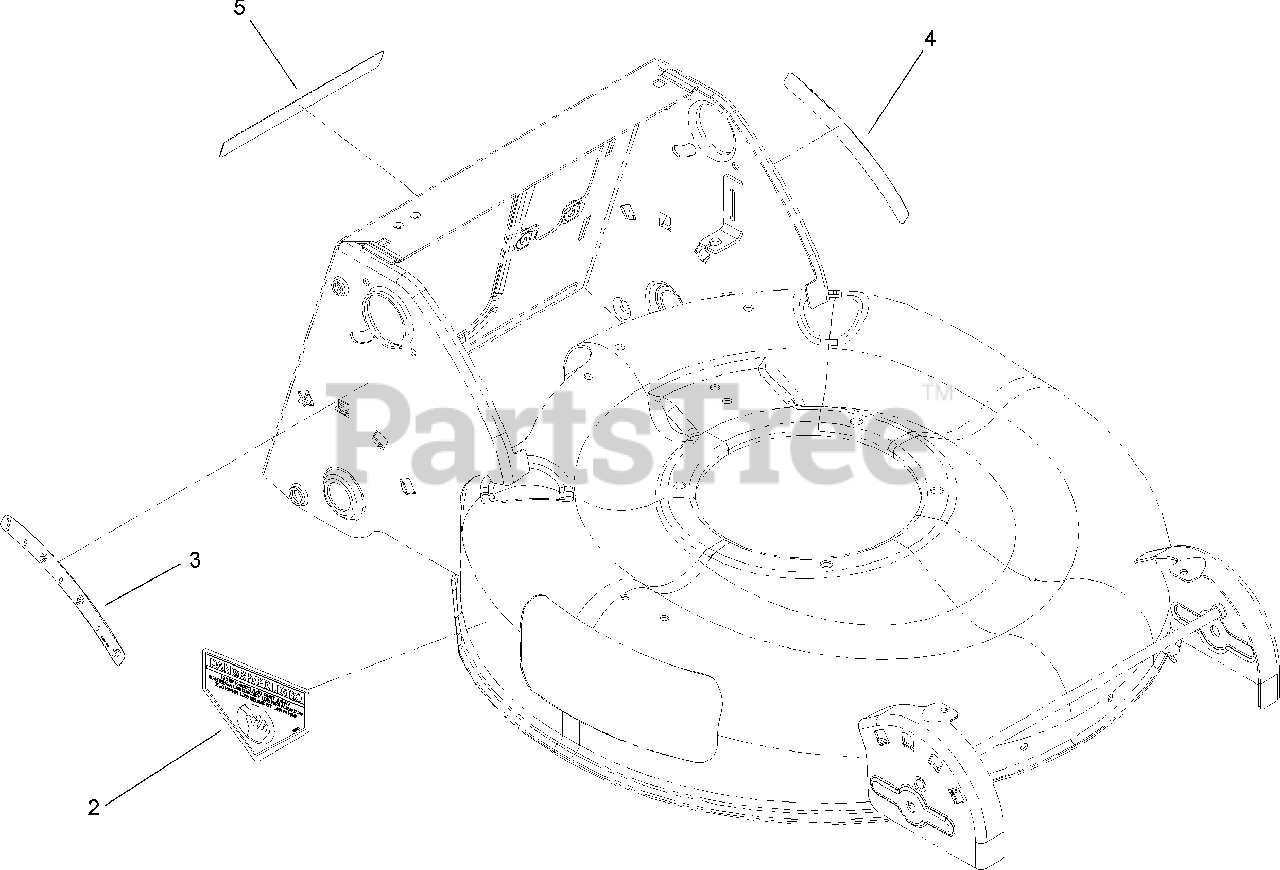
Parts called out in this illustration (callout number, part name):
2	DECAL-DANGER
3	DECAL-HOC, RH
4	DECAL-HOC, LH
5	DECAL-SAFETY
